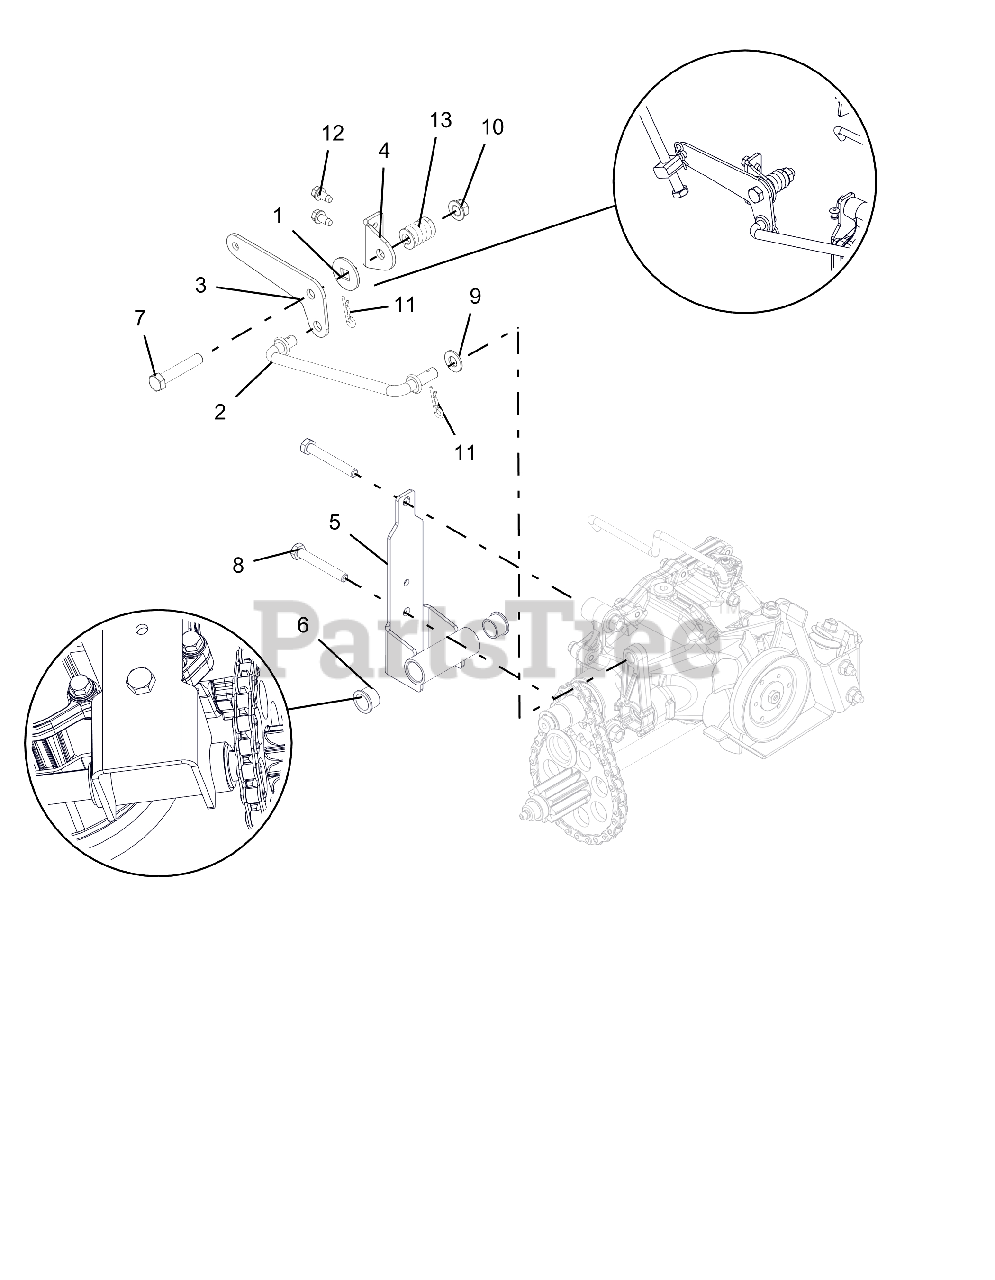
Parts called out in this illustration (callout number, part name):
1	WASHER, FRICTION
2	ROD, HYDRO TRANS SHIFT
3	PIVOT, HYDRO TRANS SHIFT
4	BRKT, HYDRO SHIFT PIVOT
5	TRANS, MOUNT , SECONDARY, WHEEL
6	BSHG, FLG .625 X .750 X .500 X .875
7	BLT-HEX .38-16X2.00 GR5 YWZC
8	BLT-HEX .31-18X2.25 GR5 YWZC
9	WSHR-FL-STL.406X.812X.065 YWZ
10	NUT, LK-TOP-FLG .38-16 YWZC
11	PIN, HAIR INT .08X.18X1.18 YWZC
12	SCR-TAP .25-20X.50 HWH TR YWZ
13	SPRG, COMPRESSION
